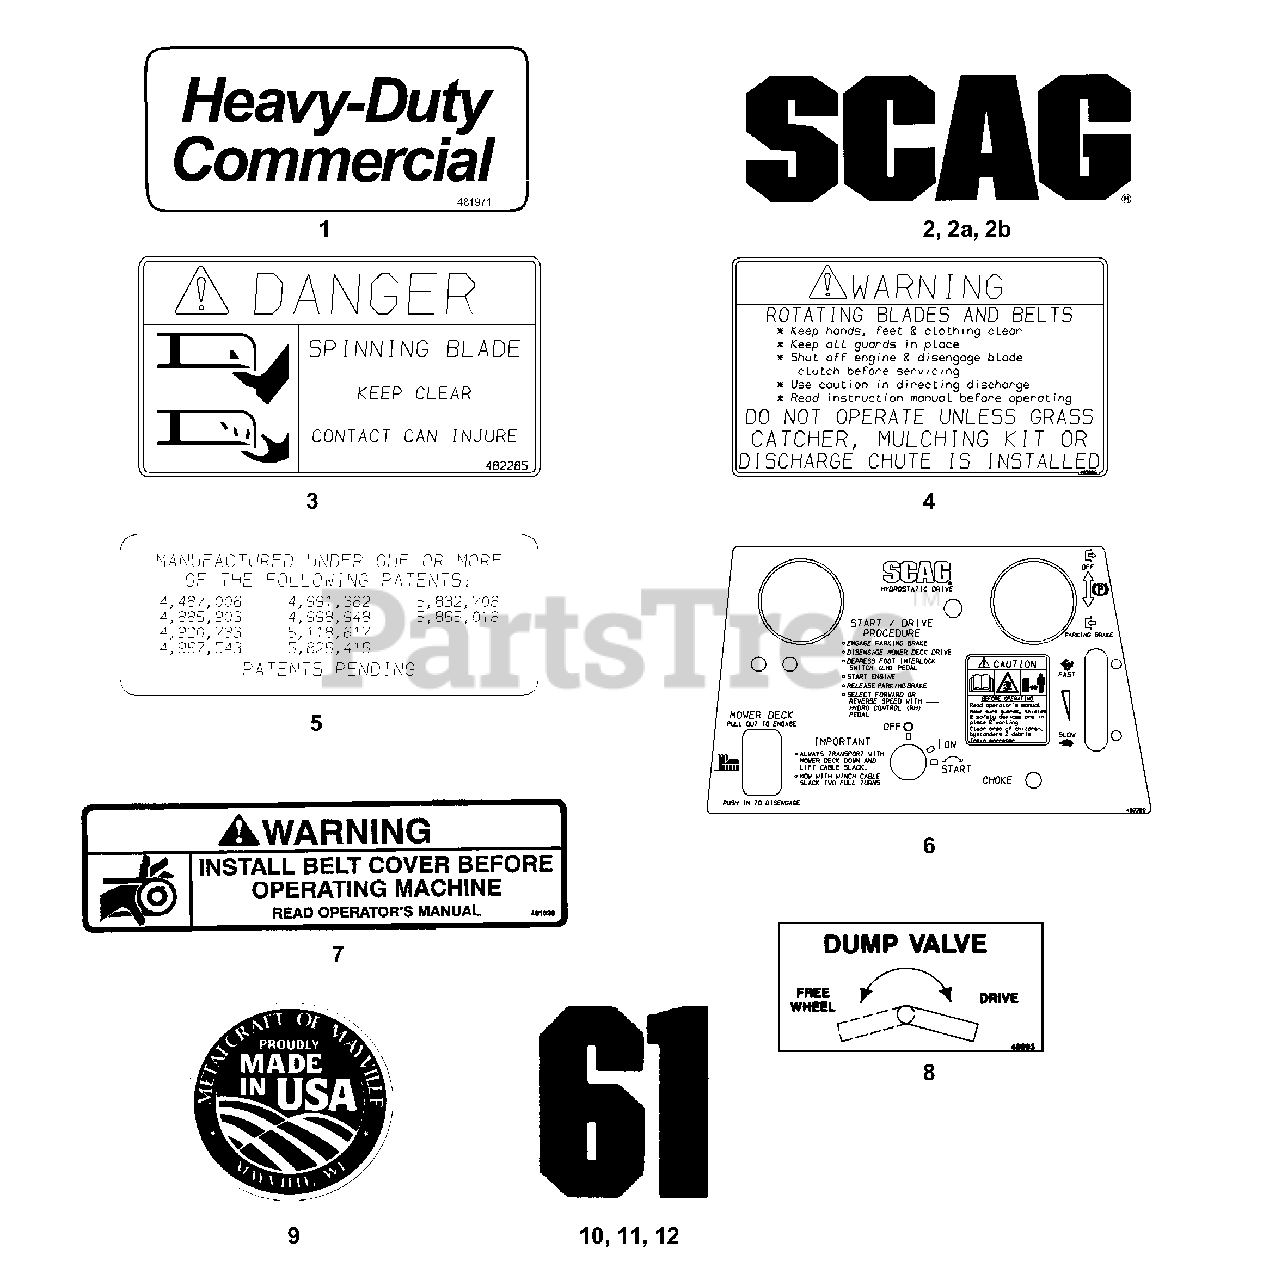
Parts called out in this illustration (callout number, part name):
1	Decal, Heavy Duty Commercial
2	Decal, Scag Logo (Cutter Deck)
2A	Decal, Scag Logo (Battery Box Front)
2B	Decal, Scag Logo Seat Back
3	Decal, Danger-Spinning Blades
4	Decal, Warning-Rotating Blades
5	Decal, Patent
6	Decal, Instrument Panel
7	Decal, Warning-Belt Cover
8	Decal, Dump Valve
9	Decal, Metalcraft-Made In USA
10	Decal, 52
11	Decal, 61
12	Decal, 72
